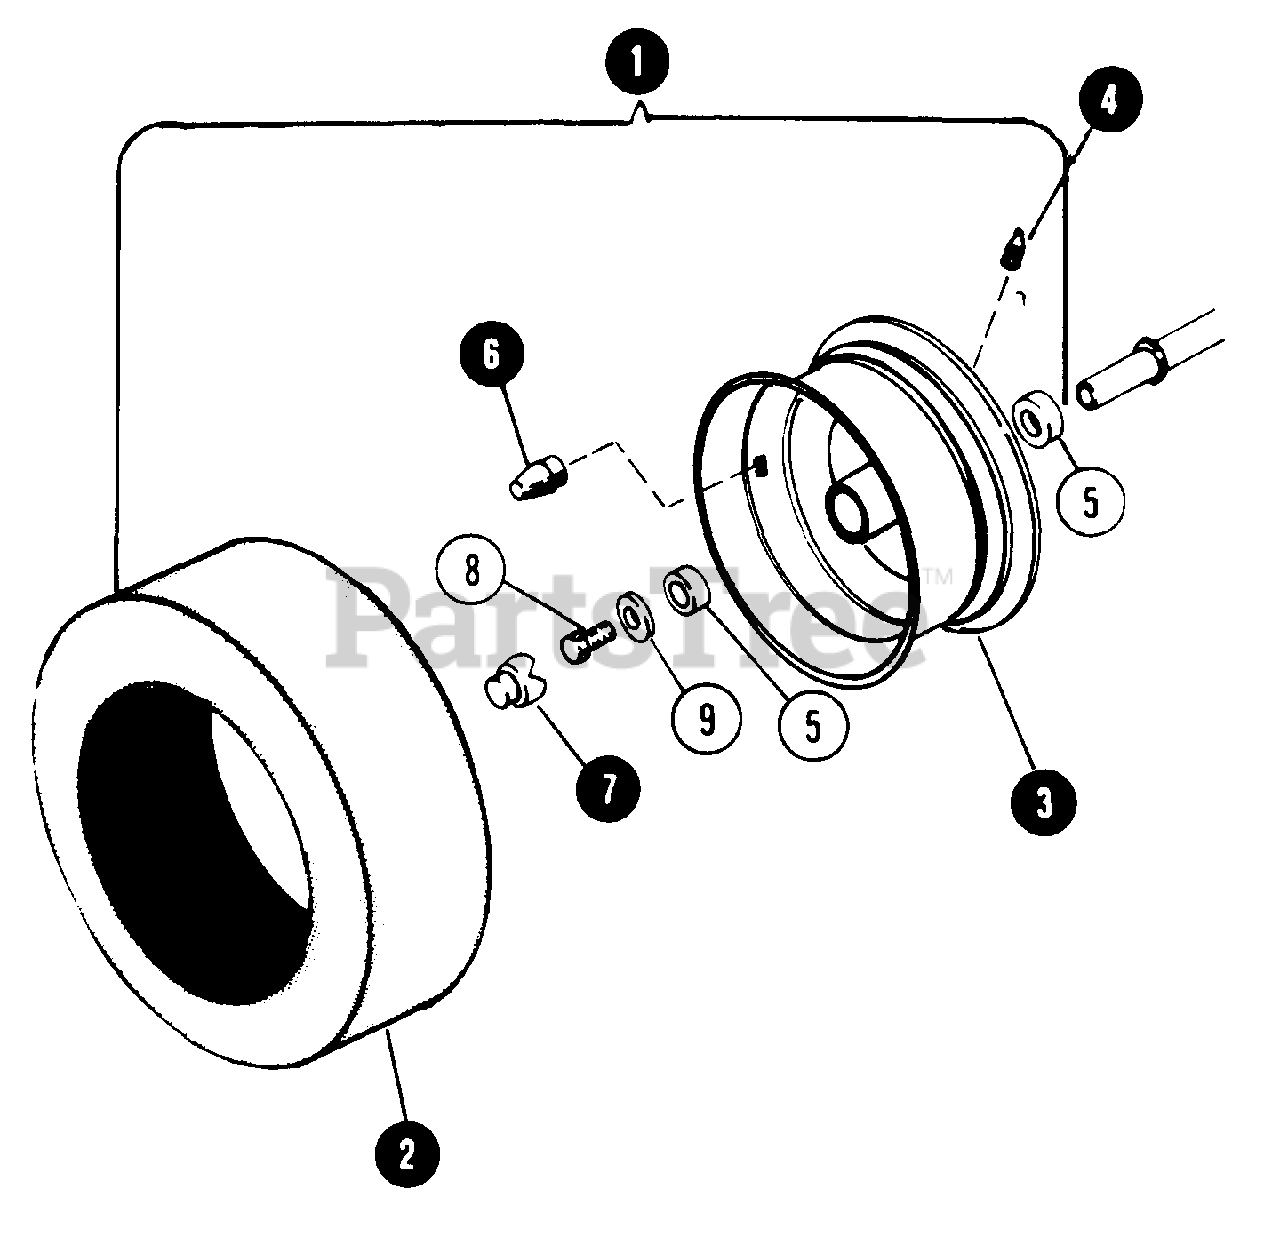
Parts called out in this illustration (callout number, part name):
1	WHEEL ASSEMBLY
2	TIRE,
3	RIM,
4	PULLEY, 8.36" O.D.
5	BEARING, BALL
6	VALVE, AIR
7	CAP, FRONT HUB
8	BOLT, 3/8C x 7/8 HEX HEAD
9	WASHER, 13/32" FLAT
